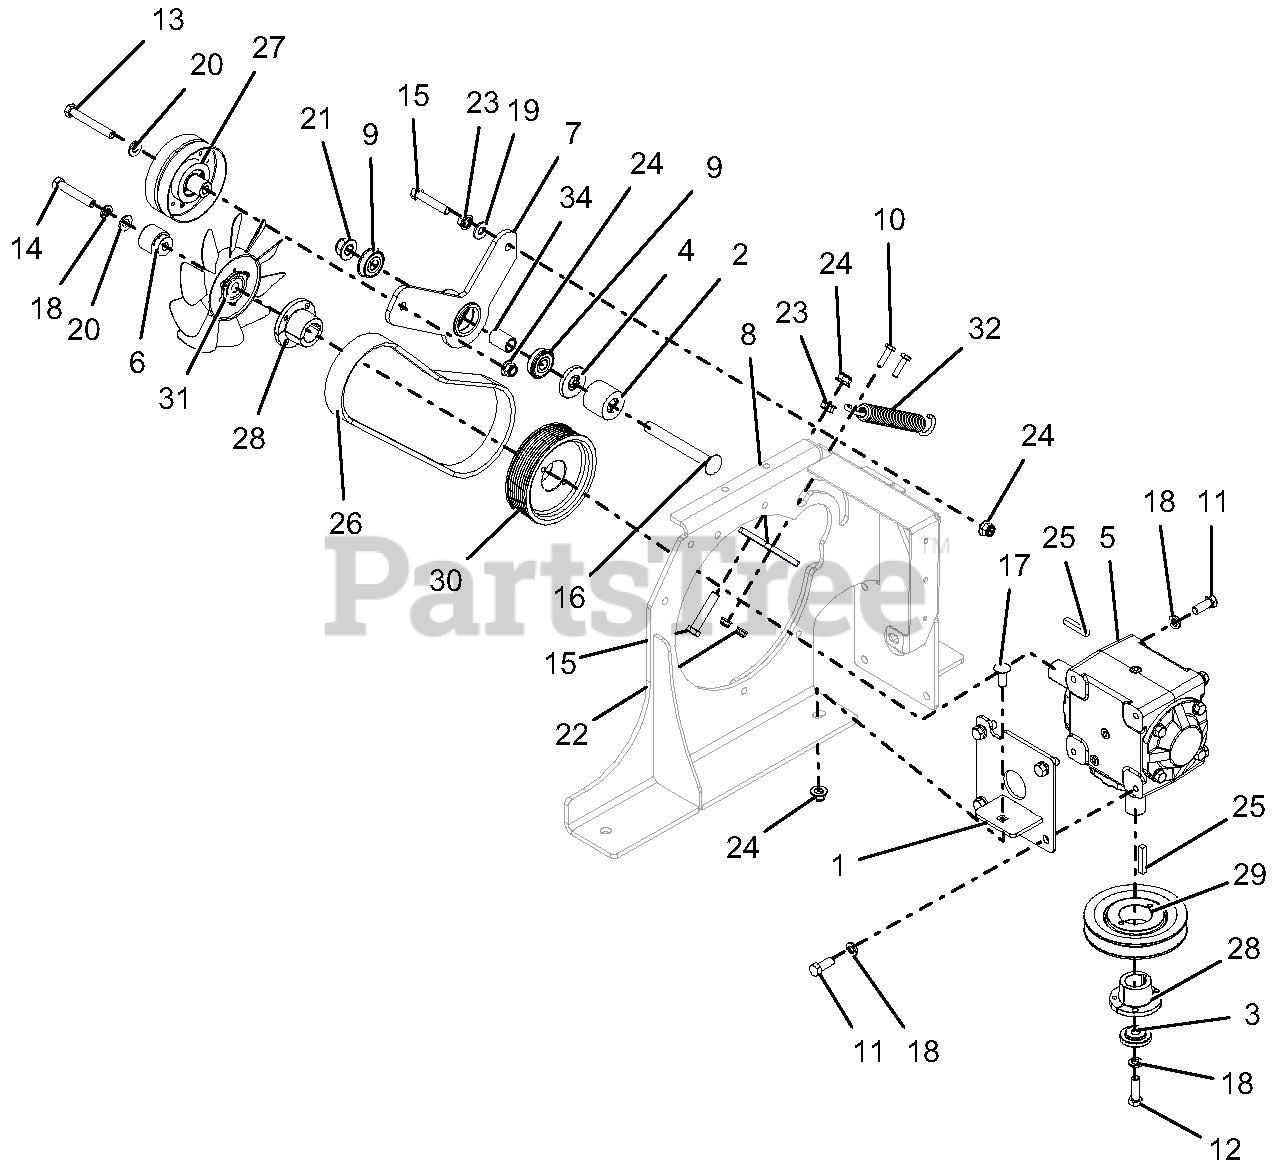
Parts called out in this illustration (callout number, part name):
1	WLDMT, GEARBOX SUPPORT
2	SPCR, PT400 DIESEL IDLER ARM
3	RETAINER, SHEAVE SPINDLE
4	SPACER, IDLER ARM
5	GEARBOX, 90 DEG. 1:1 215HD
6	HUB, FAN SPACER
7	WLDMT, DIESEL IDLER ARM
8	SPRG, ANCHOR - BLACK
9	BRG, BALL .501 X 1.38 X .438 SEALED
10	BLT-HEX .25-20X1.00 GR5 YWZC
11	BLT-HEX .38-16X1.00 GR5 YWZC
12	BLT-HEX .38-16X1.25 GR5 YWZC
13	BLT-HEX .38-16X2.75 GR5 YWZC
14	BLT-HEX .38-16X2.25 GR5 YWZC
15	BLT-HEX .38-16X2.00 GR8 YWZC
16	BLT-RDHDSQNK .50-13X4.50 G5 YWZC
17	BLT-RDHDSHSQNK.38-16X1.0 G5YZ
18	WSHR-LK .38X.094 REG YWZC
19	WSHR-FL-STL.38X.875X.083 YWZC
20	WSHR-FL-STL.406X.812X.065 YWZ
21	NUT-LK-NYL-FLG .50-13 YWZC
22	NUT-LK-NYL-FLG .25-20 YWZC
23	@NUT-SPNLK-FLG .375-16 YWZC
24	NUT-LK-NYL-FLG .38-16 YWZC
25	KEY, SQ .25 X .25 X 1.25
26	BELT, 8-RIB POLY-V
27	IDLER, IDLER FLAT 4.00 X .38
28	BSHG, TAPER LOCK 1" SHAFT
29	SHEAVE, TAPER BUSHING
30	SHEAVE, POLY -V 4.65 X 1.40
31	FAN, 7.00"-10 BLADE W/ INSERT
32	SPRG, EXTENSION
34	SPACER, .510 X .750 X 1.148
